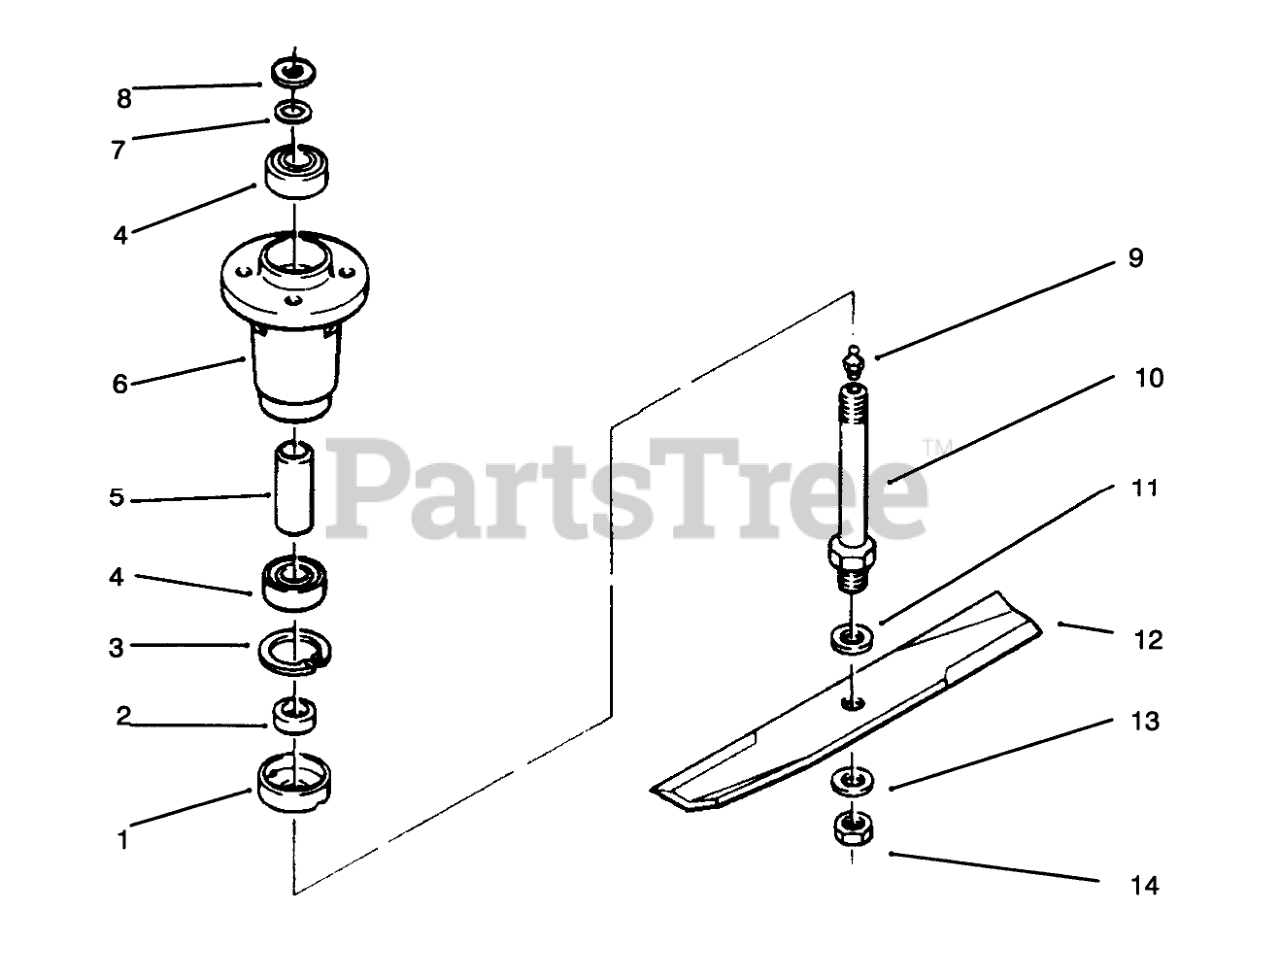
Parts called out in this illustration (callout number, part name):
1	CUP-SPINDLE
2	SPACER-BLADE
3	RING-RETAINING
4	BEARING-BALL
6	HOUSING-SPINDLE
7	O RING
8	Washer
9	FITTING-GREASE
10	SHAFT-SPINDLE
11	Washer
12	S/A BLADE KIT
13	WASHER-FLAT
14	NUT-JAM
